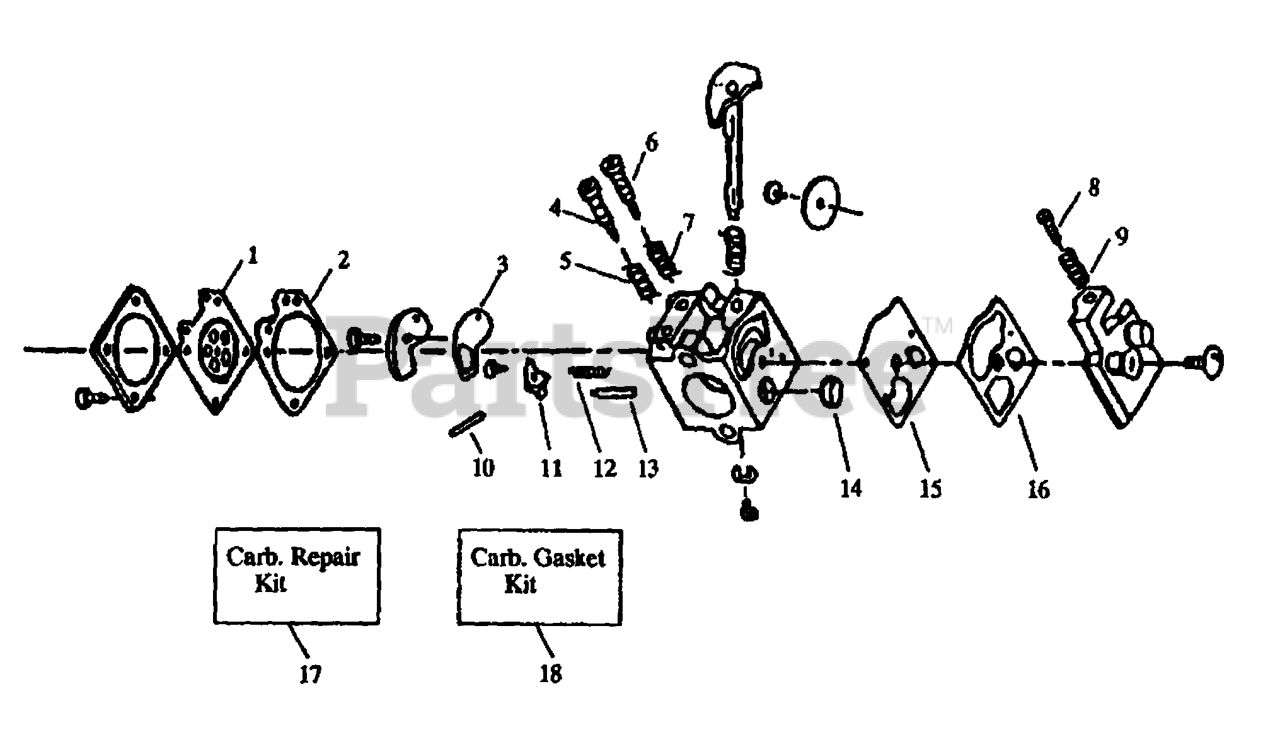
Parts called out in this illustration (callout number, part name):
1	DIAPHRAGM
2	GASKET-METER DIAP
3	GASKET-CIRCUIT PLATE
4	HI-SPEED NEEDLE
5	Hi Speed Needle Spring
6	NEEDLE - IDLE
7	SPRING-NEEDLE FUEL MIX
8	SCREW-IDLE SPEED
9	SPRING-IDLE SPEED
10	PIN
11	LEVER
12	SPRING-METERING LEVER
13	INLET NEEDLEVALVE
14	SCREEN-DUTCH TWILL INLE
15	DIAP FUEL PUMP
16	GASKET-FUEL PUMP
17	REPAIR KIT
18	KIT-KWIK REPAIR
